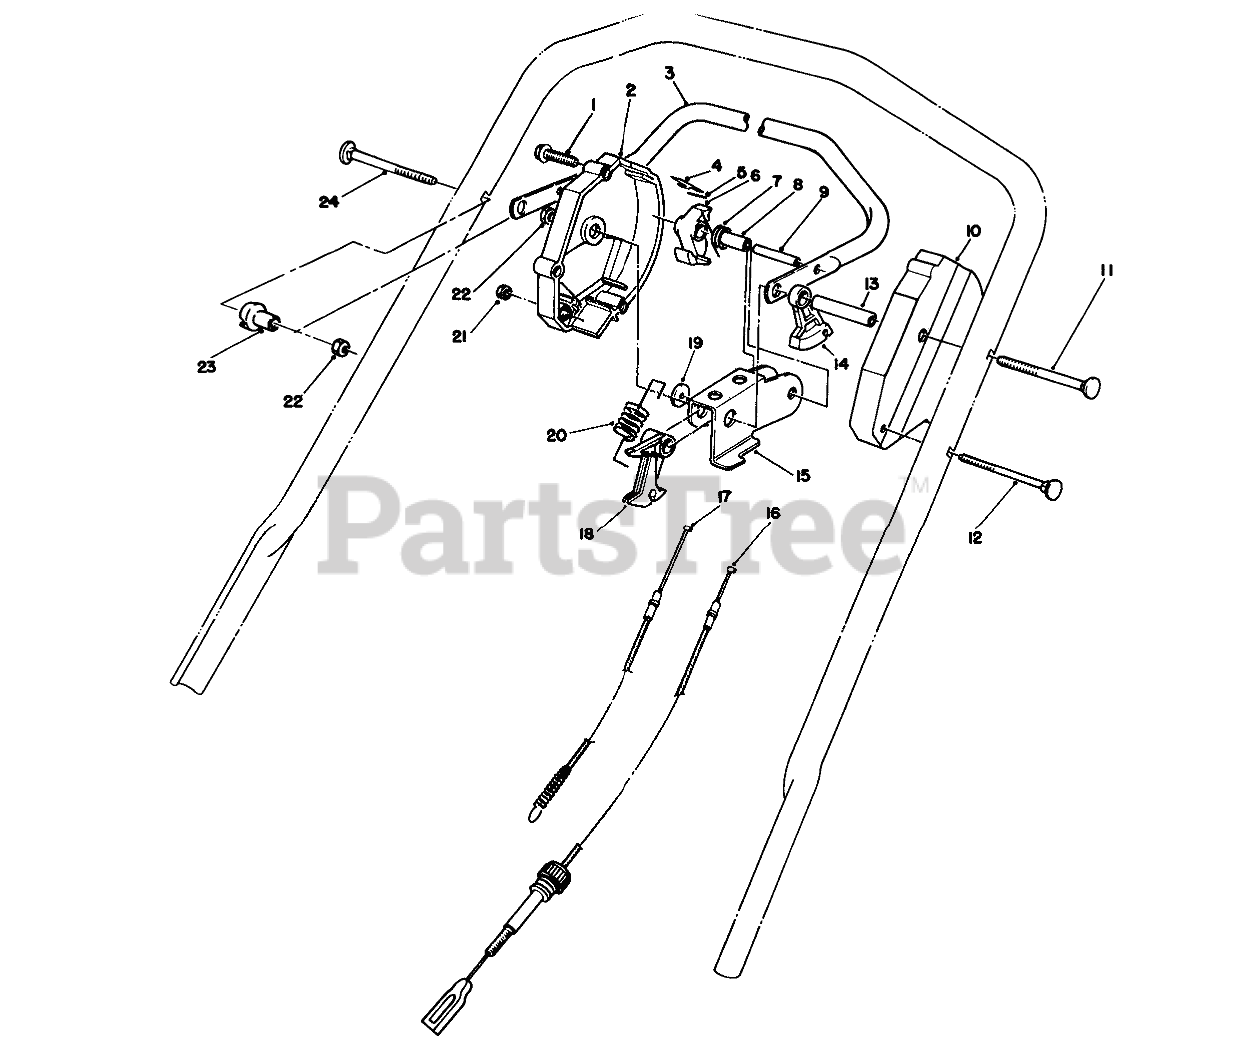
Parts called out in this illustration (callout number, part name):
1	SCREW-HWHTF
2	Housing-Control R.H. (Incl Ref. #4 & 5)
3	Bar-Control
4	SPRING-LEAF
5	PIN-INSERT
6	HOOK-CONTROL
7	SPRING-TORSION
8	SPACER
9	PIN-ROLL, SLOTTED
10	HOUSING-CONTROL, LH
11	5/16-18 X 3 HNDLE SCREW
12	HANDLE SCREW
13	TUBING-SPACER
14	LEVER-TRACTION
15	ROCKER
16	TRACTION CABLE
17	CLUTCH CABLE
18	LEVER-CABLE
19	WASHER-NYLON
20	SPRING-DETENT
21	NUT-HEX
22	NUT-LOCK, NI
23	SPACER-SUPPORT
24	5/16-18 X 2 HNDLE SCREW
